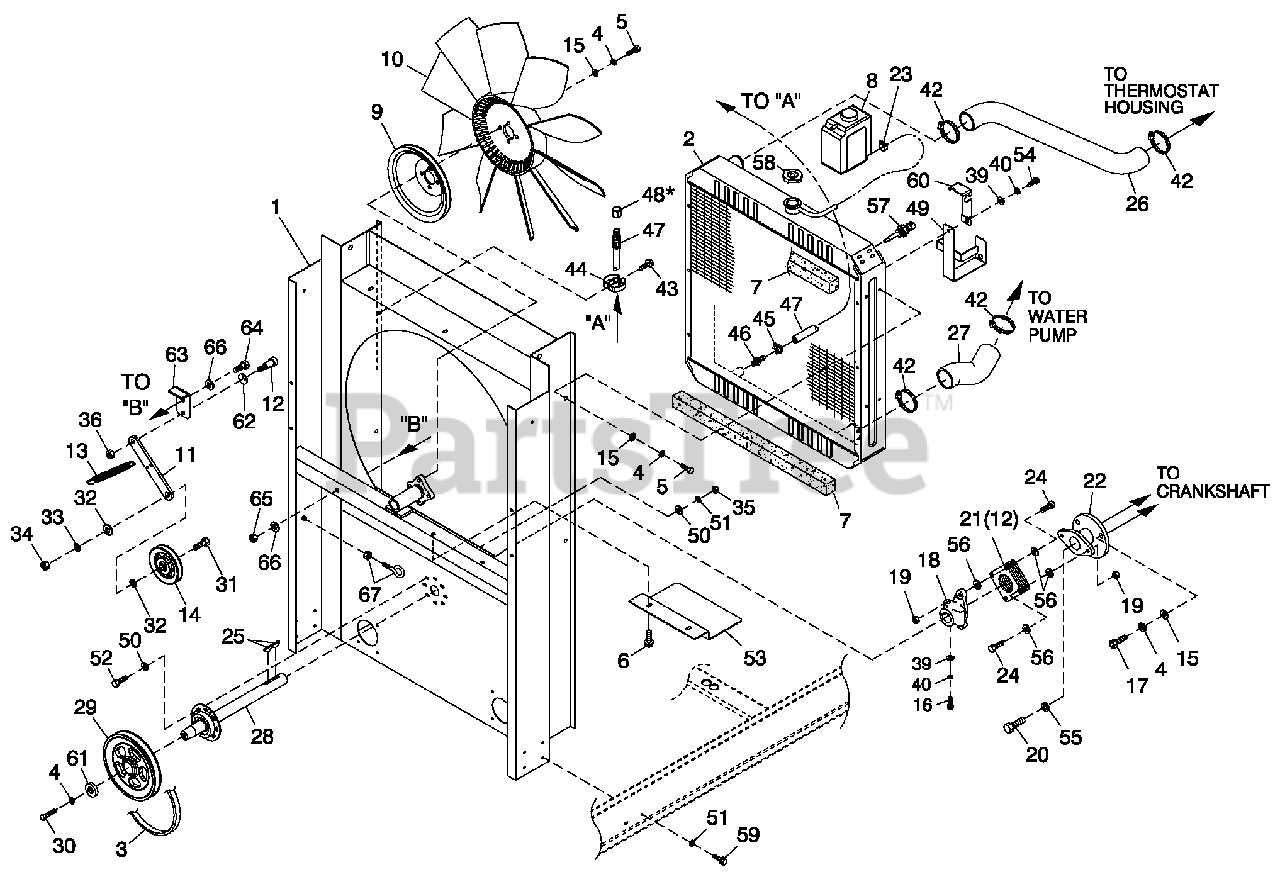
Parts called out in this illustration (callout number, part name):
1	WELDMENT RADIATOR SUPP0RT150
2	RADIATOR 680 X 680 X 70 CPL
3	V-BELT 31/64' 1 X 62-3/8' 1
4	WASHER LOCK M10
5	SCREW HHCM10-1.5X20 G8.8
6	SCREW THF M6-1 X 16 N WA Z/JS
7	TAPE FOAM 1 X 1 (26.75" LG)
8	TANK COOLANT RECOVERY
9	PULLEY FAN V-GROOVE 9M
10	FAN 26M LH ROTATION
11	FLAT TENSIONER ARM
12	SHOULDER BOLT 3/8 X 1/2' 1
13	SPRING TENSION CPL
14	PULLEY V-BELT 4' 1 FLANGED
15	WASHER FLAT 3/8-M10 ZINC
16	SCREW HHC M8-1.25 X 35 G8.8
17	SCREW SHC M10-1.5X 35 G12.9
18	HUB FLEX PLATE
19	NUT HEX LOCK 5/16-24 NY INS
20	SCREW HHC M12-1.5X 60 G8.8
21	DISK FLEX
22	COUPLING HUB FLEX (MACH)
23	CLAMP HOSE BAND 1/4
24	SCREW HHC 5/16-24X1.124
25	KEY WOODRUFF 4 X 1 9 D
26	HOSE RADIATOR UPPER CPL
27	HOSE LOWER RAD CPL C5 6.8L
28	A SSY BRG/SHAFT CPL FANDRIVE
29	PULLEY 6.5M DIA MACHINED (6.8L 100KW)
30	SCREW HHC M10-1.5X 30 G8.8
31	SCREW HHC 1/2-13X2 1 1 G8
32	WASHER FLAT 1/2 ZINC
33	WASHER LOCK 1/2
34	NUT HEX 1/2-13 STEEL
35	NUT HEX M6 X 1.0 G8 YEL CHR
36	NUT HEX LOCK 5/16-18 NY INS SS
39	WASHER FLAT 5/16-M8 ZINC
40	WASHER LOCK M8-5/16
42	CLAMP HOSE #28 1.32-2.25
43	SCREW HHTT M4-0.7 X 8 BP
44	SPRING CLIP HOLDER.37-.62
45	CLAMP HOSE .38-.87
46	BARBED STR 3/8 NPTX3/8
47	HOSE DRAIN A SSY 28M
48	CAP HEX 1/4 NPT BRASS
49	BRACKET COOLANT TANK
50	WASHER FLAT 1/4-M6 ZINC
51	WASHER LOCK M6-1/4
52	SCREW HHC M6-1.0X 20 G8.8
53	SHIELD RADIATOR C5
54	SCREW HHC M8-1.25 X 20 G8.8
55	WASHER LOCK M12
56	WASHER FLEX (THIN)
57	PROBE, COOLANT LEVEL 3/8 NPTF
58	CAP RADIATOR 13 PSI
59	SCREW HHFCM6-1.0X 20 G8.8
60	BRACKET, SIGNAL CONDITIONER
61	SPACER .5 X 1.5 X .25 STL/ZINC
62	WASHER BELLEVILLE .75X.38X.028
63	BENT 90 TENSIONER ARM SUPPORT
64	SCREW HHC M8-1.25 X 75 C8.8
65	NUT HEX LOCK M8-1.25 NY INS
66	WASHER FLAT 5/16-M8 ZINC
67	EYEBOLT 3/8-16X3.5'' TURNED
